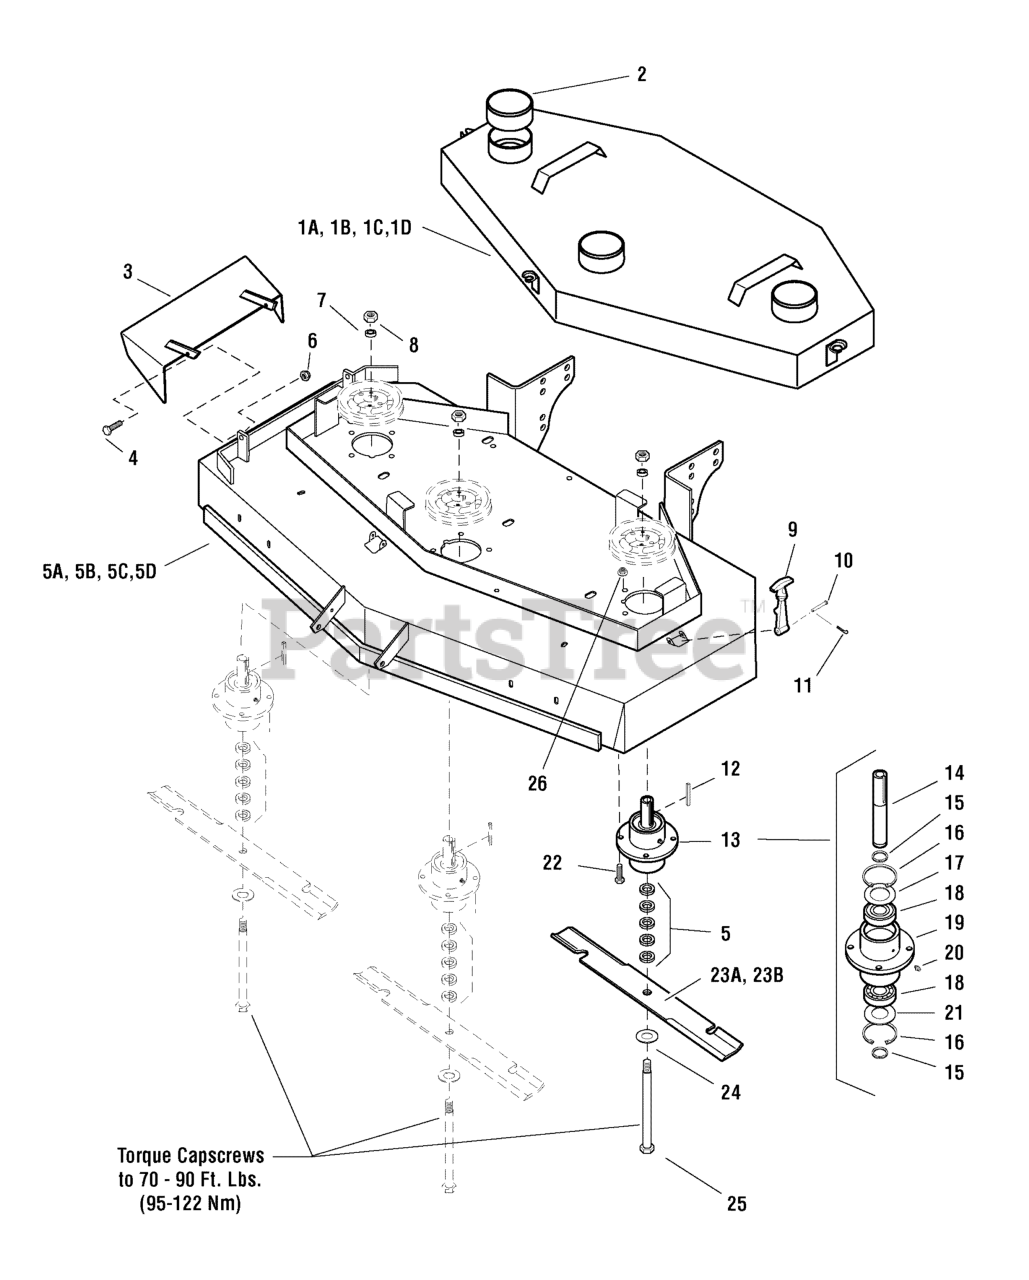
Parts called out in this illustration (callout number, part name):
1A	48" DECK GUARD
1B	48" DECK GUARD
1C	52" DECK GUARD
1D	52" DECK GUARD
2	VINYL CAP
3	CHUTE, DISCHARGE WELDMENT
4	BOLT, 5/16-18 X 1 GD5 YZ
5A	48" MOWER HOUSING
5B	48" MOWER HOUSING ASSEMBLY
5C	52" MOWER HOUSING
5D	52" MOWER HOUSING ASSEMBLY
6	NUT, 5/16-18 Hex Nylon Lock
7	SPACER, .63 x 1.06 x .23
8	NUT, 5/8-11 Hex
9	RUBBER LATCH
10	CLEVIS PIN
11	COTTER PIN
12	KEY, 1/4 SQ. X 2-1/2
13	SPINDLE ASSEMBLY, Complete
14	SPINDLE SHAFT
15	SNAP RING, External
16	SNAP RING, Internal
17	SPINDLE WASHER, Top
18	BEARING
19	SPINDLE HOUSING
20	GREASE FITTING
21	SPINDLE WASHER, Bottom
22	BOLT, Flange Head, 5/16-18 x 1-1/4
23A	MOWER BLADE, 18"
23B	MOWER BLADE, 16-1/4"
24	WASHER, 5/8" USS
25	BOLT, 5/8-11 x 9-1/2
26	NUT, 5/16-18 Hex Nylon Flange
